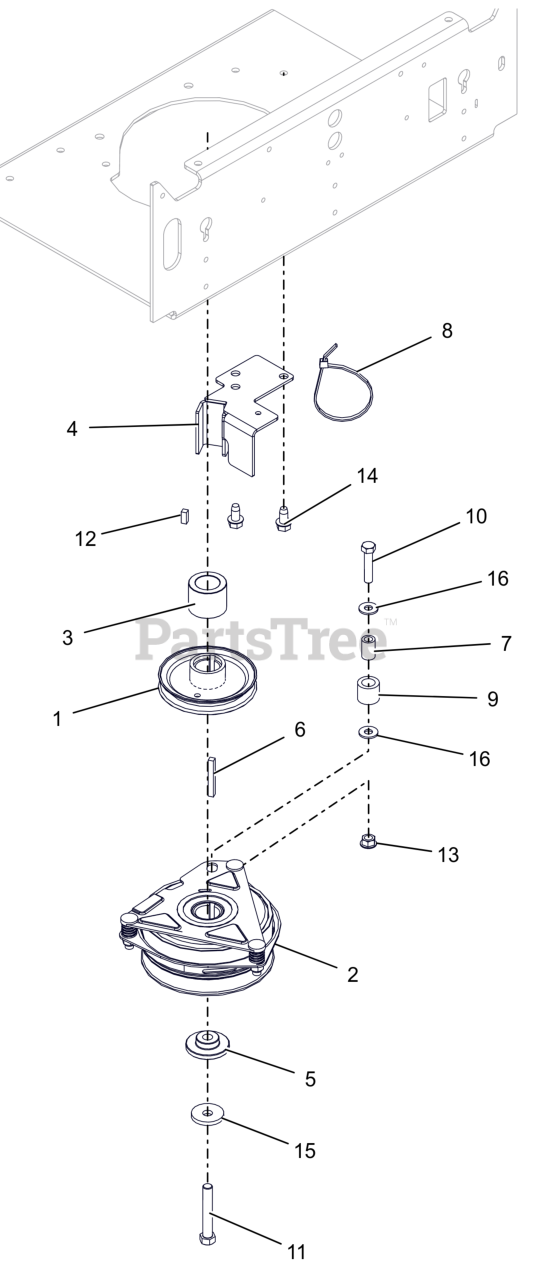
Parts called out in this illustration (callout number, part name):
1	PULLEY, 4.50 OD X 1.127 ENGINE
2	CLUTCH, OGURA GT2.5-FE02
3	SPACER, 1.125 X 1.75 X 1.40
4	CLUTCH STOP BRKT - BLACK
5	BSHG-FLG .469X1.06X.574X2.0
6	KEY-STR .25X2.0X.25
7	BUSH.,S.391X.622X.950 ST
8	CABLE TIE LG 5-1/2
9	BUMPER,RUBBER .62X1.0X.88 LG
10	BLT, HEX .38-16X1.75 G5 ZCC
11	BLT, HEX 0.4375-20X2.75 G8 ZCC NT
12	KEY-SQ .25X.625X.25 SAE 8630
13	NUT-LK-TOP-FLG .38-16 ZC120
14	SCR,TAP .375-16X.75 HWH TR ZCC
15	WASHER, 7/16" SPRING DISK
16	WSHR,FLT .375X.875X.083 ZCC
